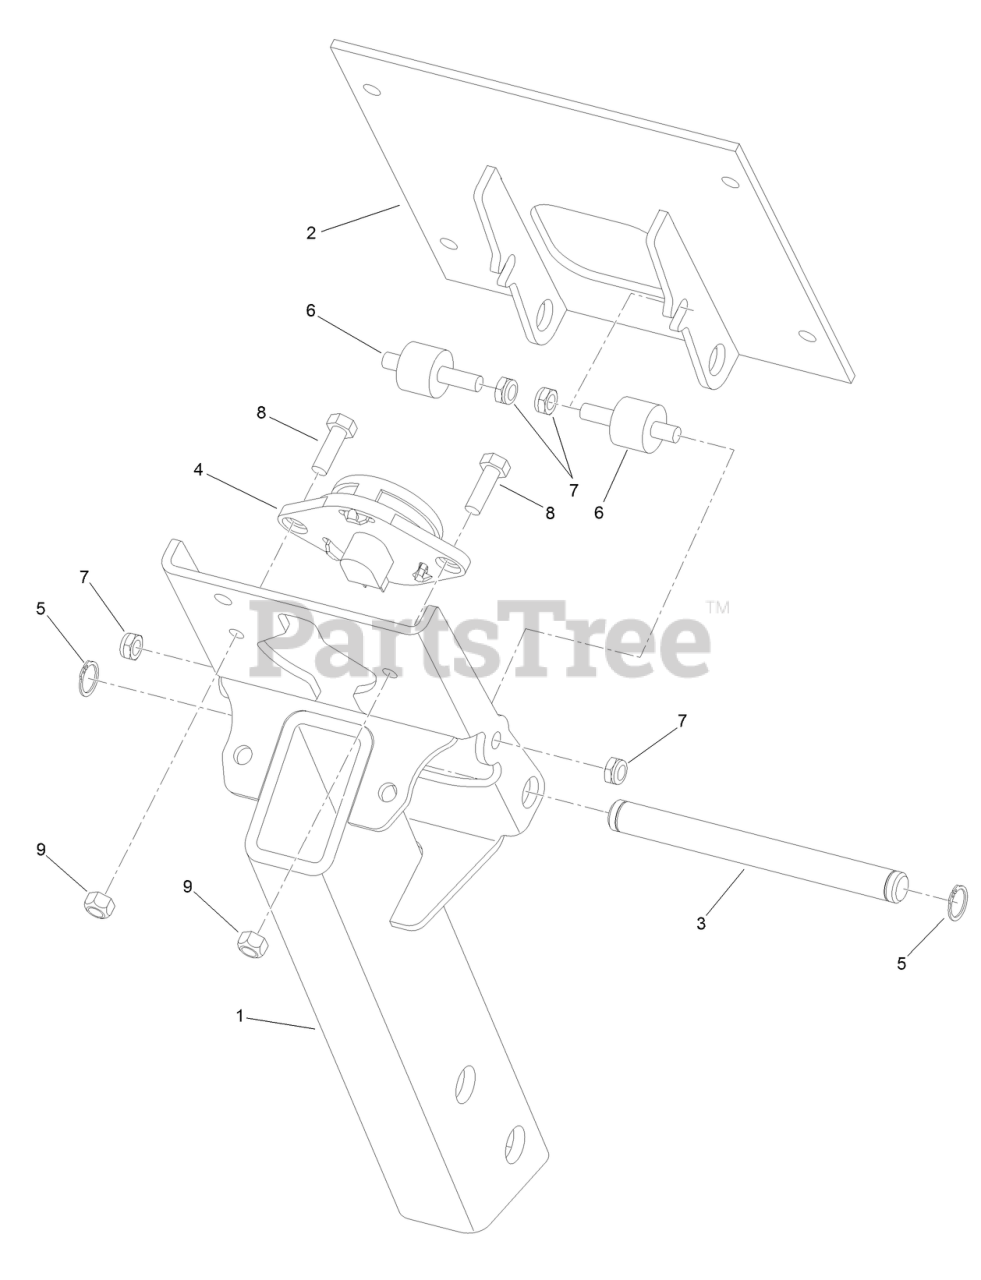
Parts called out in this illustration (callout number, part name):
1	POST-SEAT
2	PAN-SEAT
3	PIN-PIVOT
4	SWITCH-SEAT
5	RING-SNAP, EXTERNAL
6	MOUNT-RADIATOR
7	NUT-LOCK, NI
8	SCREW-HH
9	NUT-LOCK, NI
